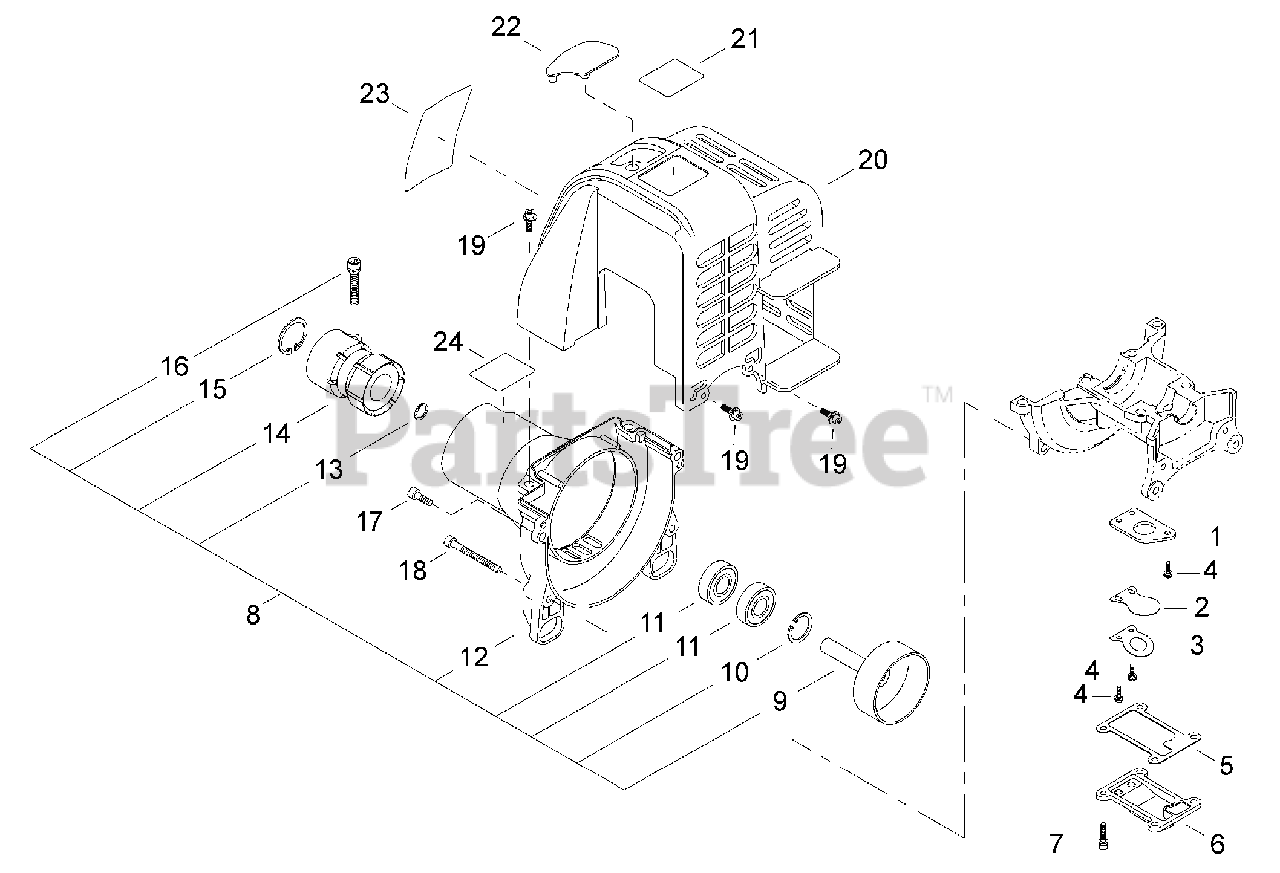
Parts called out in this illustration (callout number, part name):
1	PLATE, REED BACKING
2	VALVE, REED
3	STOP, REED VALVE
4	SCREW - 3X10
5	GASKET, REED VALVE
6	COVER, REED VALVE
7	SCREW - 4X12
8	FAN CASE ASSY
9	DRUM, CLUTCH
10	RING, RETAINING - 26
11	BEARING, BALL - 6000
12	CASE, FAN
13	RING, RETAINING
14	CUSHION
15	RING, RETAINING - 40
16	SCREW - 5X22
17	SCREW - 5X16
18	SCREW - 5X35
19	SCREW - 4X16
20	COVER, ENGINE
21	LABEL - MODEL CT2510
22	COVER, SPARK PLUG
23	LABEL - C4
